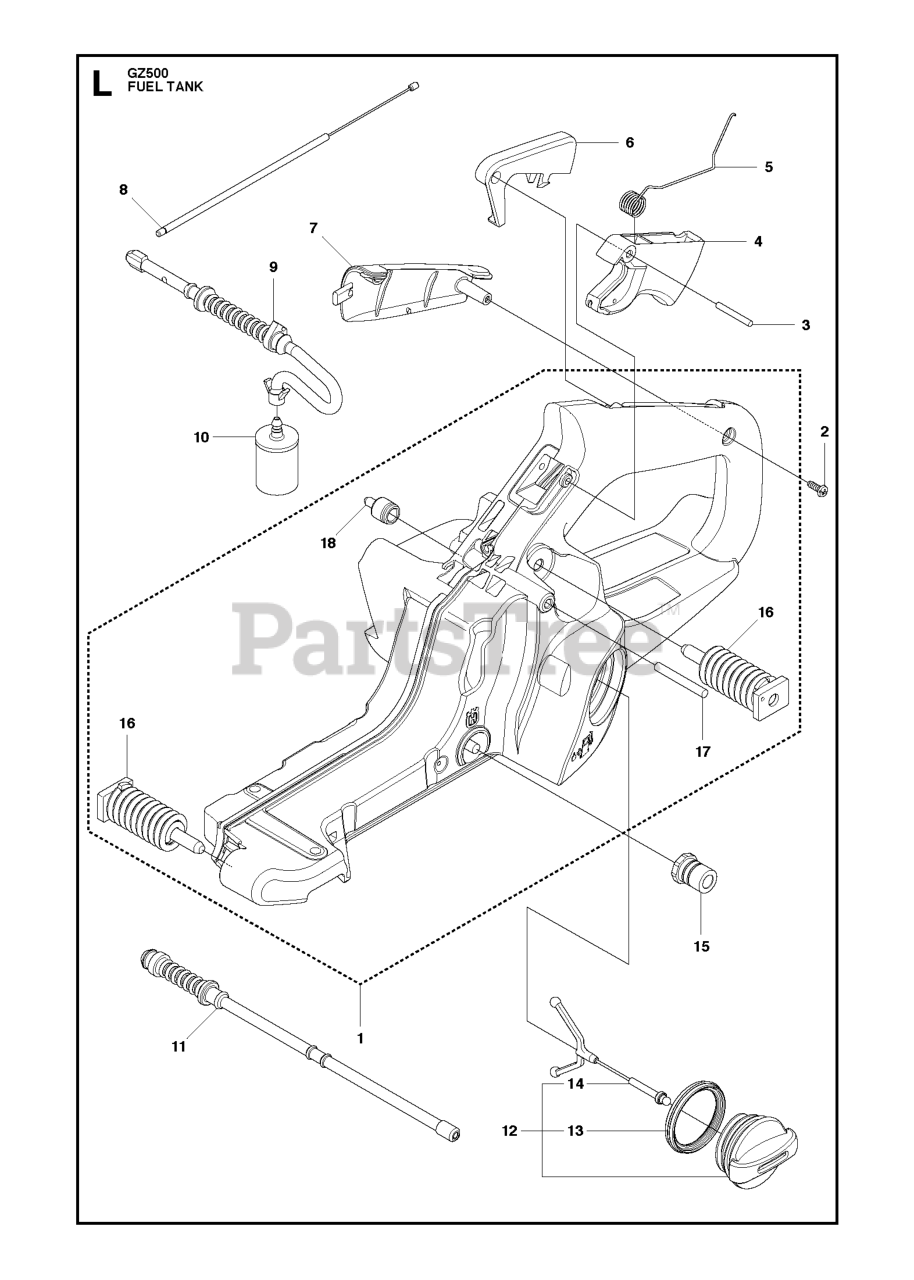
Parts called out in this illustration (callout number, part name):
1	FUEL TANK ASSY
2	SCREW CCRPANT
4	THROTTLE TRIGGER
6	THROTTLE LOCKOUT
7	HANDLE INSERT
8	THROTTLE CABLE ASSY
9	FUEL HOSE
10	FUEL FILTER
11	RETURN HOSE
12	TANK CAP ASSY
14	TANK LOCK
15	LATERAL SUPPORT
16	ANTI VIBRATIONS ELEMENT
17	GROOVED PIN
18	FUEL TANK VENT
